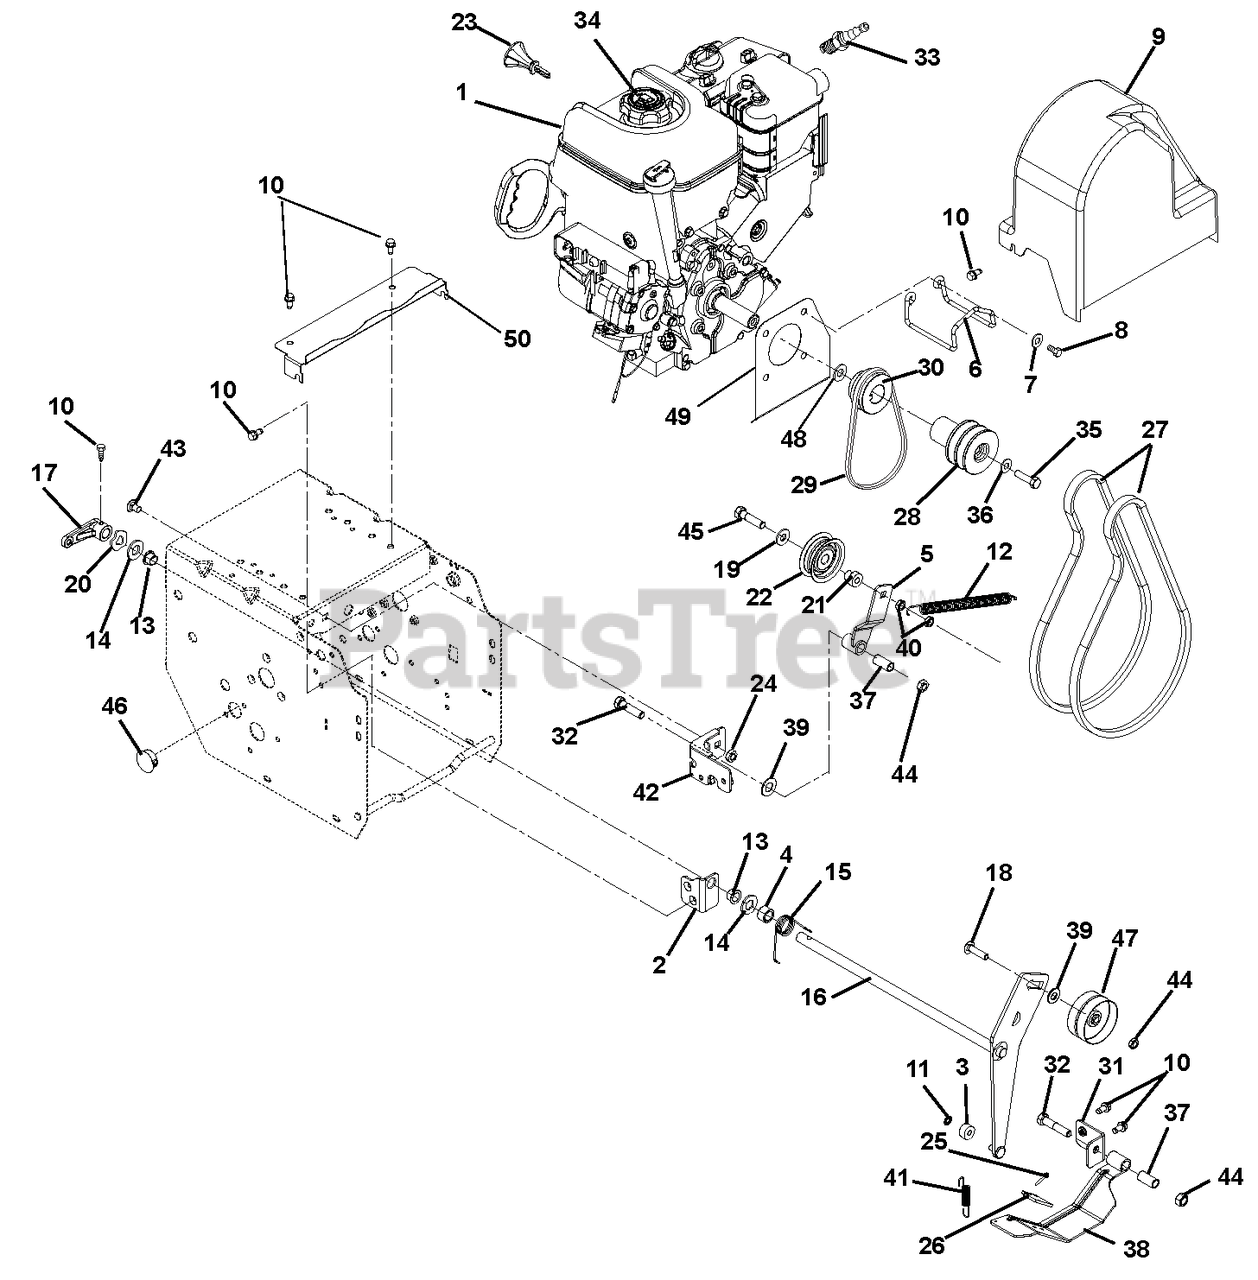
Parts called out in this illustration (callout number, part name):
1	ENGINE,BRIGGS 20 SNOW MAX 120V
2	BRACKET, MOUNT - IDLER ARM
3	BSHG,SLV .270 X .750 X .250
4	BSHG-SLV .510X.751X.475
5	WELDMENT, TRACTION IDLER ARM
6	FINGER, BELT
7	WSHR-LK .312X.097 HVY YWZC
8	BLT-HEX .31-24X.75 YWZC GR5
9	PLZ SEE SERVICE LETTER #L-2166
10	SCR-TAP .25-20X.50 HWH TR YWZ
11	RG-RTNG-EXT .250X.010
12	SPRING, SWIVEL HOOK EXTENSION
13	BUSHING, POLYLINER-.50 SPLIT
14	WSHR-FL-STL.531X1.00X.063 YWZC
15	SG-TORS .075 X .955
16	WELDMENT, ATTACHMENT IDLER ARM
17	ARM, CLUTCH - ATTACHMENT
18	@BLT-RHDSSQNK .38-16X1.75 G5YZ
19	@WSHR-FL-STL.38X.875X.083 YWZC
20	WSHR-WAVE .50X.75X.015 .13FRHT
21	SPCR, BRG .315X.50X.688X.281
22	IDLER
23	KEY, IGNITION PUSH/PULL B&S
24	@NUT-LK-TOP-FLG .31-18 YWZC
25	RVT-POP .187 YZ
26	PAD, BRAKE
27	V-BELT, HA-RAW EDGE (SET)
28	SHEAVE, ATTACHMENT 2-GRV
29	V-BELT, 3L-WRAPPED
30	SHEAVE, DRIVE
31	BRACKET, BRAKE MOUNT
32	@BLT-HEX .38-16X1.75 GR5 YWZC
33	PLUG, SPARK
34	CAP, FUEL - BRIGGS
35	BLT-HEX .38-24X2.25 YWZC GR5
36	@WSHR-LK .38X.094 REG YWZC
37	BSHG-SLV .385X.500X1.045
38	BRAKE ARM W/PAD
39	@WSHR-FL-STL.406X.812X.065 YWZ
40	@NUT-LK-CTR-JAM .31-18 YWZC
41	SPRING-EXT .047 X .438 X 1.85
42	WELDMENT, FRAME BRACKET
43	@BLT-RHDSSQNK .31-18X.62 G5YZ
44	@NUT-LK-TOP-FLG .38-16 YWZC
45	@BLT-HEX .31-18X1.50 GR5 YWZC
46	PLUG, HOLE - .875" NYLON
47	IDLER-FLAT 2.75X.38 PAINTED
48	WSHR-FL-STL- 1.062X2.0X.134 YZ
49	BAFFLE, PRIMARY WATER
50	BAFFLE, SECONDARY WATER
